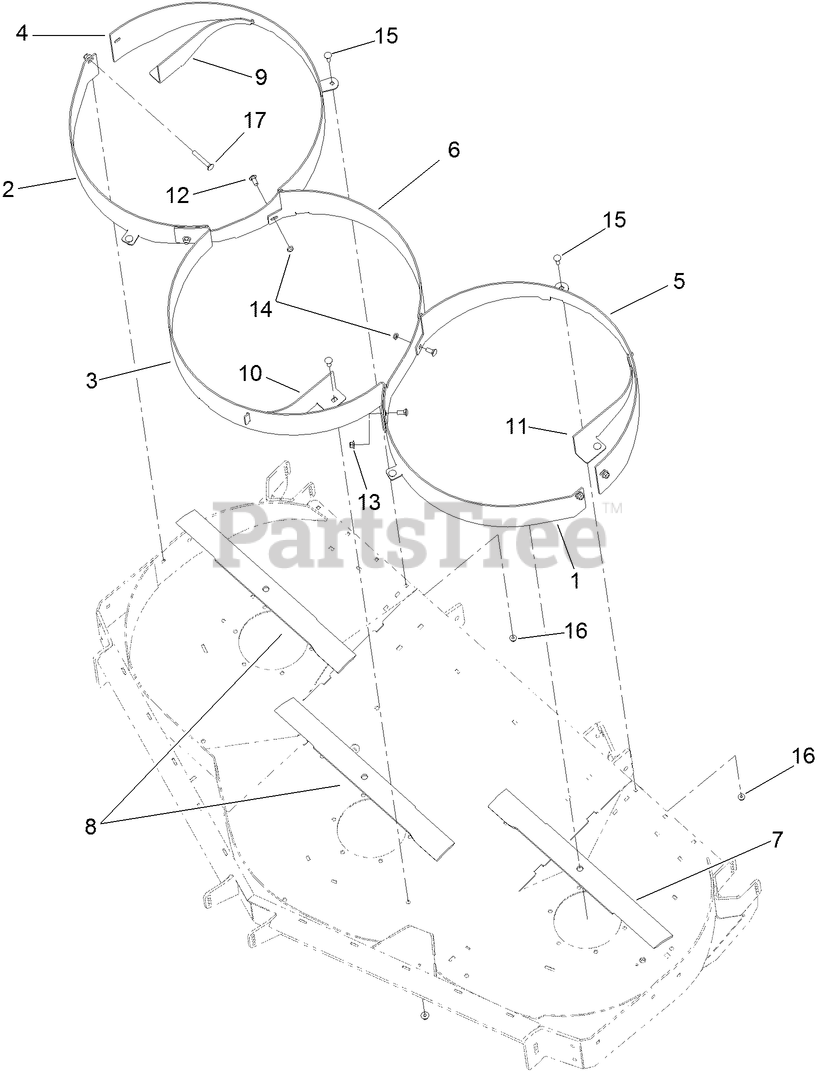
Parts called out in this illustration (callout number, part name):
1	BAFFLE-MULCH, FRONT RH
2	BAFFLE-MULCH, FRONT LH
3	BAFFLE-MULCH, FRONT CENTER
4	BAFFLE-MULCH, REAR LH
5	BAFFLE-MULCH, REAR RH
6	BAFFLE-REAR, CENTER
7	BLADE-ROTARY, 24.5IN LOW FLOW (COUNTER ROTATION)
8	BLADE-LO FLOW, 24.5IN
9	BAFFLE-KICKER, LH
10	BAFFLE-KICKER, FRONT CENTER
11	BAFFLE-KICKER, RH
12	BOLT-CARR
13	NUT-HF, NI
14	NUT-LOCK, NI
15	BOLT-CARR
16	NUT-HF, NI
17	SCREW-CARR
